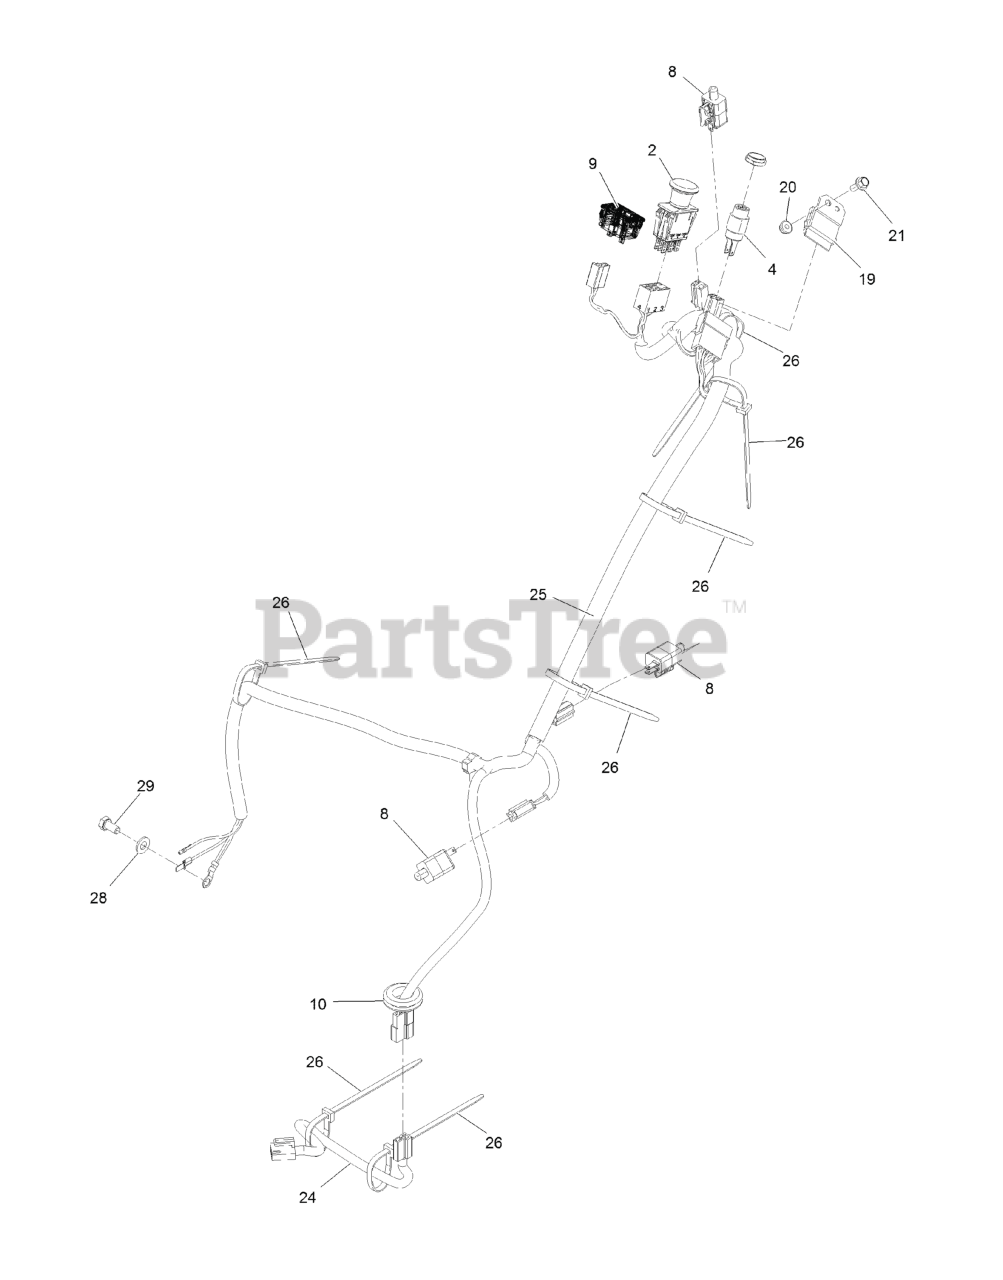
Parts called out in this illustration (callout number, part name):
2	SWITCH-PTO
4	SWITCH & KEY (INCLUDES NU
4	NUT-SWITCH, IGNITION
9	METER-HOUR
10	GROMMET
19	MODULE-INTERLOCK
21	SCREW-HHF
24	HARNESS-CLUTCH PIGTAIL
25	HARNESS-MAIN
26	TIE-PLASTIC
28	WASHER-PLAIN
29	SCREW-HH
